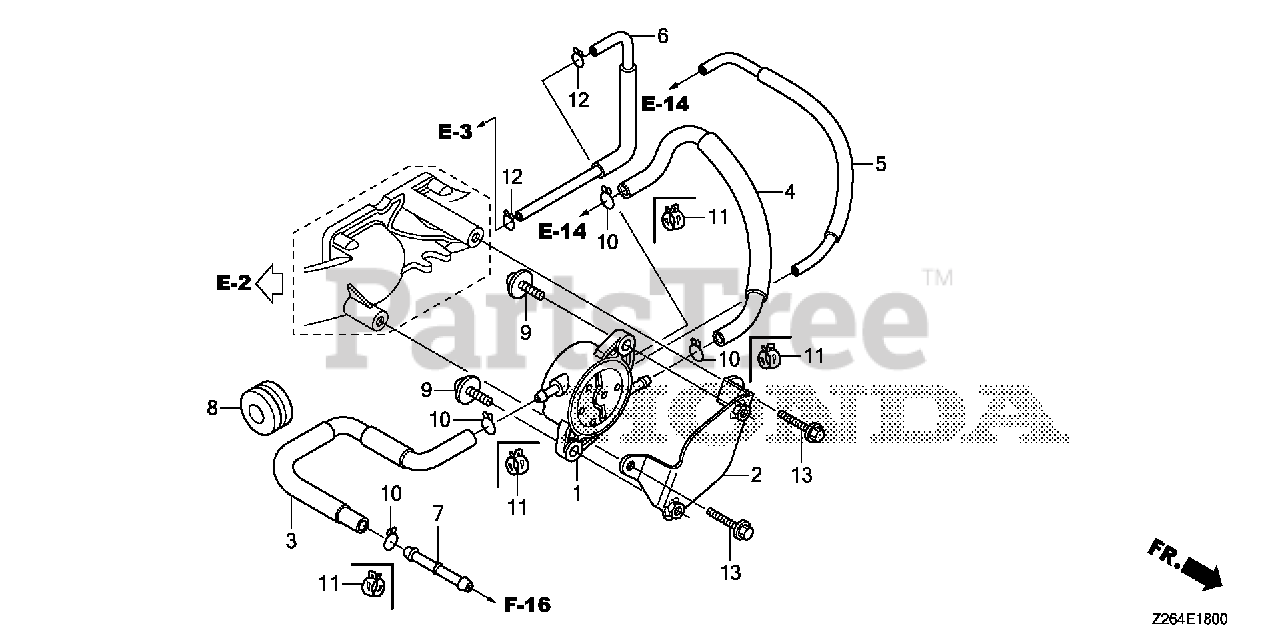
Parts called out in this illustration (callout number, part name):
1	PUMP ASSY., FUEL (MSDS)
2	STAY, FUEL PUMP
3	TUBE A, FUEL (FKM)
4	TUBE B, FUEL (FKM)
5	TUBE, PURGE
6	TUBE, DIAPHRAGM
7	JOINT, FUEL RETURN
8	RUBBER, RR. FENDER
9	SCREW-WASHER (6X16)
11	CLAMP, TUBE (D10)
12	CLIP, TUBE (C11)
13	BOLT, FLANGE (6X14)
